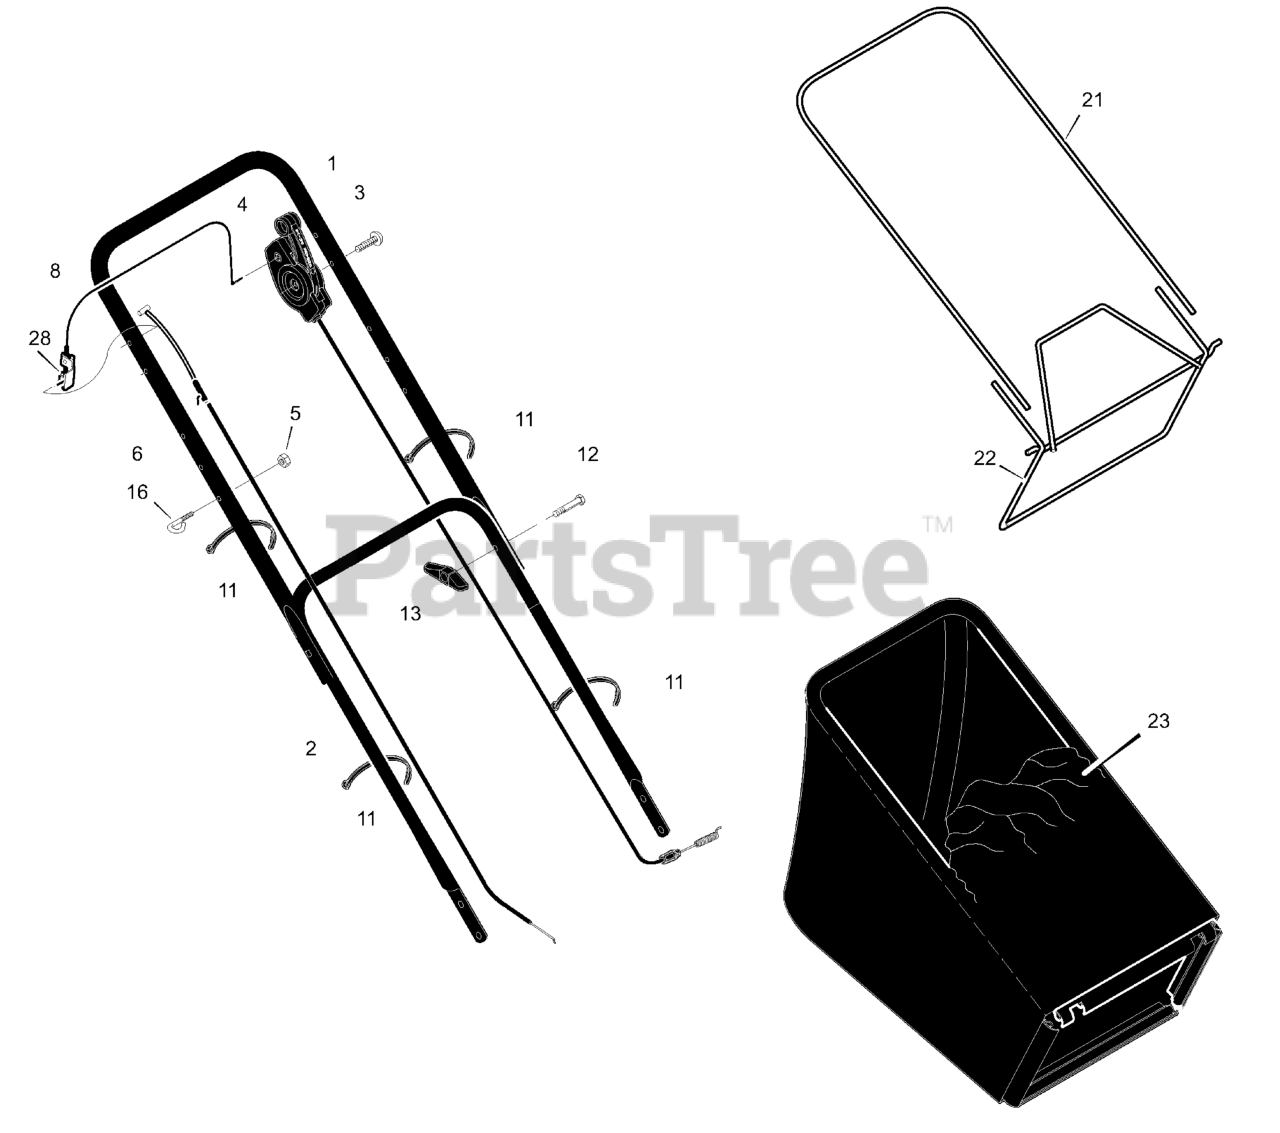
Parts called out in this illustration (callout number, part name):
1	Handle, Upper
2	Handle, Lower
4	Control, Drive
5	Locknut
6	Cable, Stop
8	Engine Stop Lever
11	Fastener, Cable
13	Knob
16	Guide, Rope
21	Frame, Top
22	Frame Assembly
23	Bag, Cloth
28	Bracket, Stop Lever
